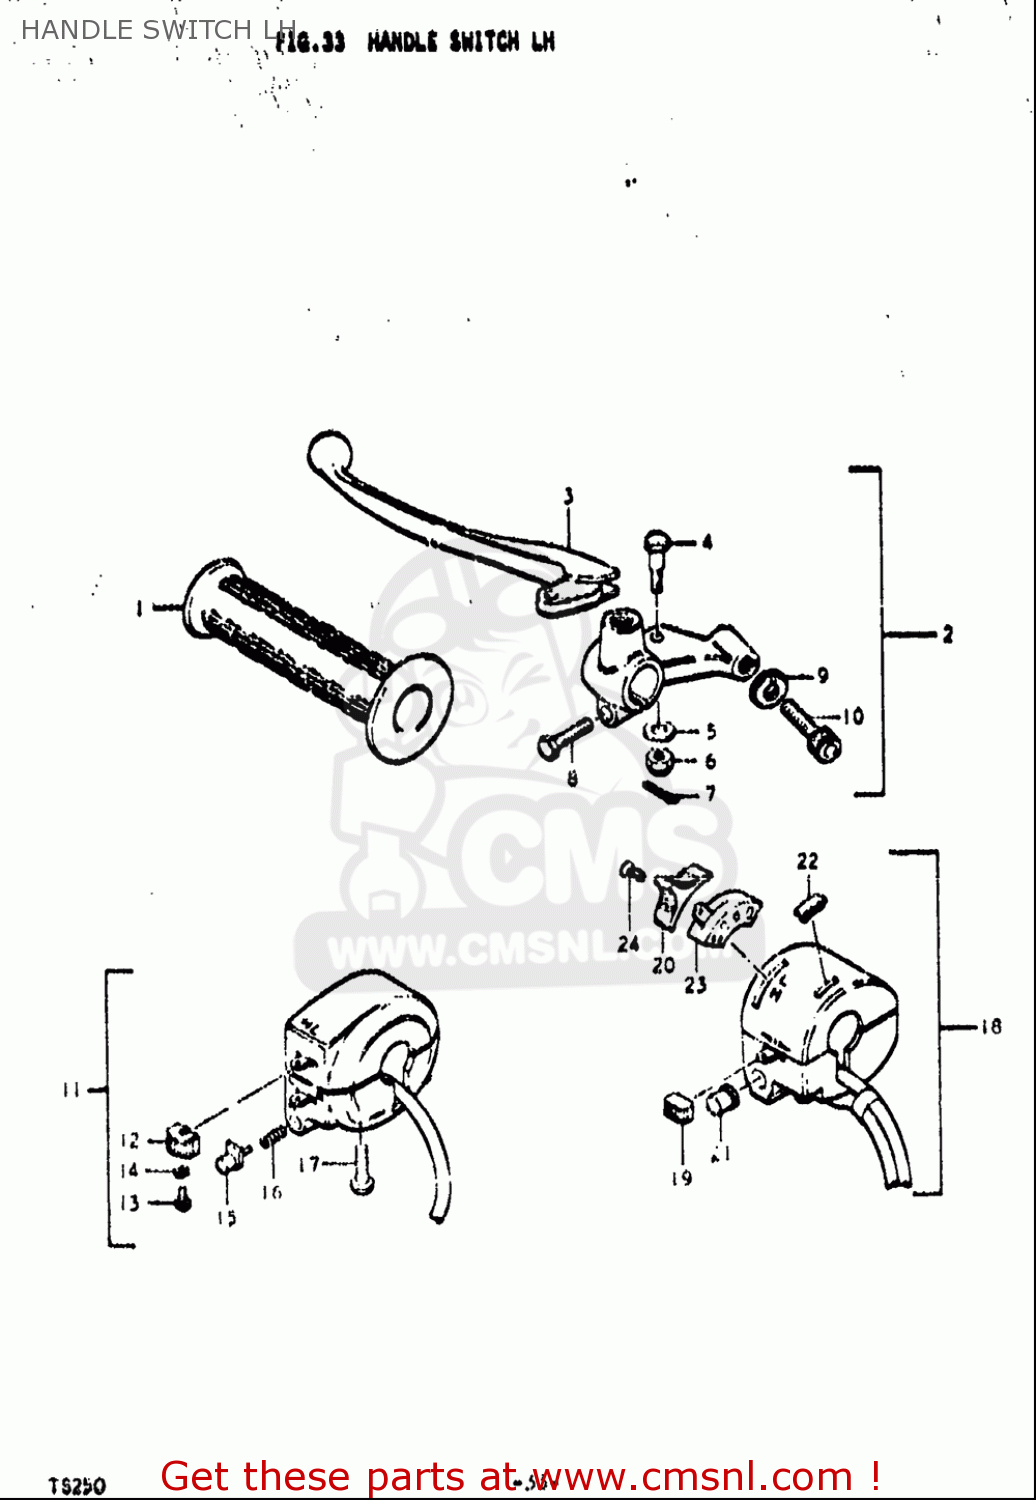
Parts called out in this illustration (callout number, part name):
1	GRIP
2	LEVER ASSY,CLUTCH
3	LEVER,CLUTCH
4	BOLT,LEVER PIVOT
5	WASHER,LOCK
6	NUT,LEVER FITTNG
7	PIN 16X20
8	BOLT
9	NUT,CABLE ADJUSTER
10	ADJUSTER,CABLE
12	KNOB,HANDLE SWITCH,UPPER
13	SCREW
14	WASHER,LOCK
15	BUTTON,HORN
16	SPRING,BUTTON
17	SCREW(5X27)
19	KNOB,HANDLE SWITCH
21	BUTTON, HORN
24	SCREW
